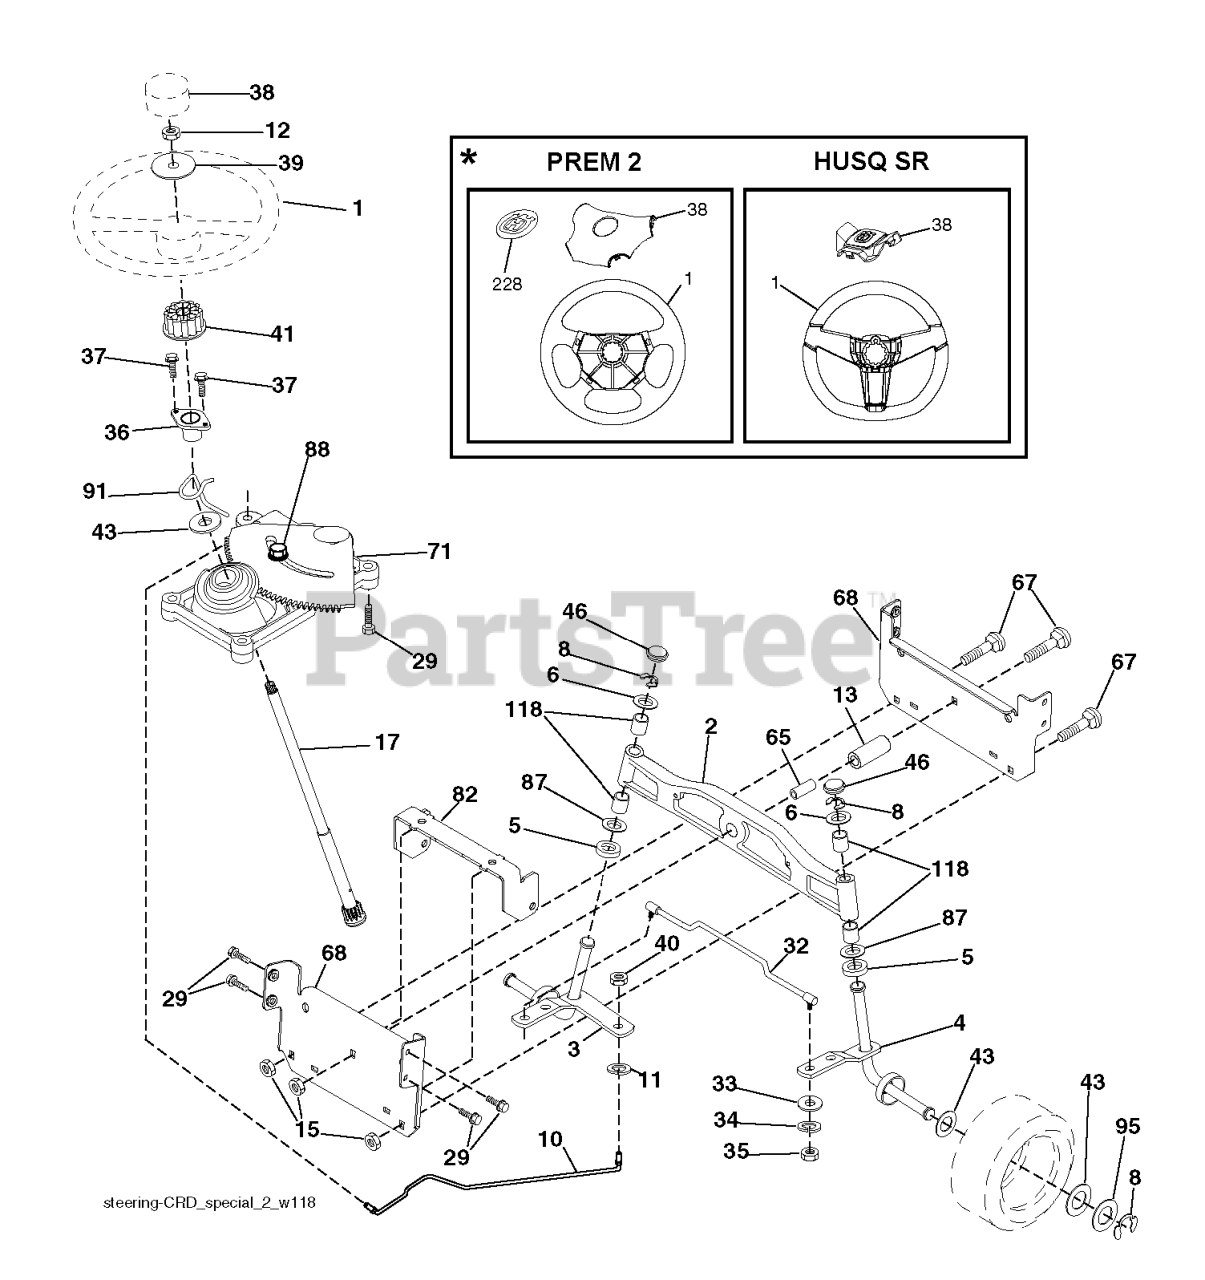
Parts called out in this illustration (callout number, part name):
1	RP WHEEL.STEER.HUSQ.PREM.OVMLD
2	AXLE.ASM.LT.CAST.LGHTWGHT
3	SPINDLE.ASM.LH.15"TIRES
4	SPINDLE.ASM.RH.15"TIRES
5	THRUST WASHER
10	DRAGLINK.15".TIRES.2001
11	WASHER, LOCK 3/8
12	NUT.HEX.1/2-20
13	TUBE, PIVOT AXLE
15	NUT
17	SHAFT ASM STRG
29	SCREW, 3/8-16X3/4
33	WASHER M
34	WASHER.LOCK.HVY.HLCL.SPR.5/16
35	NUT, CROWNLOCK
36	BUSHING, STRG. BLK
37	SCREW.TT.#10-32X.5.3/8.FLANGE
38	RP INSERT.CAP.WHL.STRG.HUSQ.
39	WASHER 9/16"ID, 2 3/8"OD
40	NUT CROWNLOCK 3/8-24
41	ADAPTER, WHEEL STNG..
46	CAP.SPINDLE.BLACK
65	SPACER.BRACE.AXLE
67	BOLT CARRIAGE
68	BRACE.AXLE.15"TIRES
71	STEERING ASM
82	BRACKET.SUSP.CHASSIS.FRONT.15
87	WASHER, FLAT .781 X 1 1/2"
88	BOLT, SHOULDER 7/16-20
91	CLIP.STEERING
95	WASHER.HARDENED
118	BUSHING, AXLE CAST
228	DECAL.WHEEL.STRG.LGN.H
